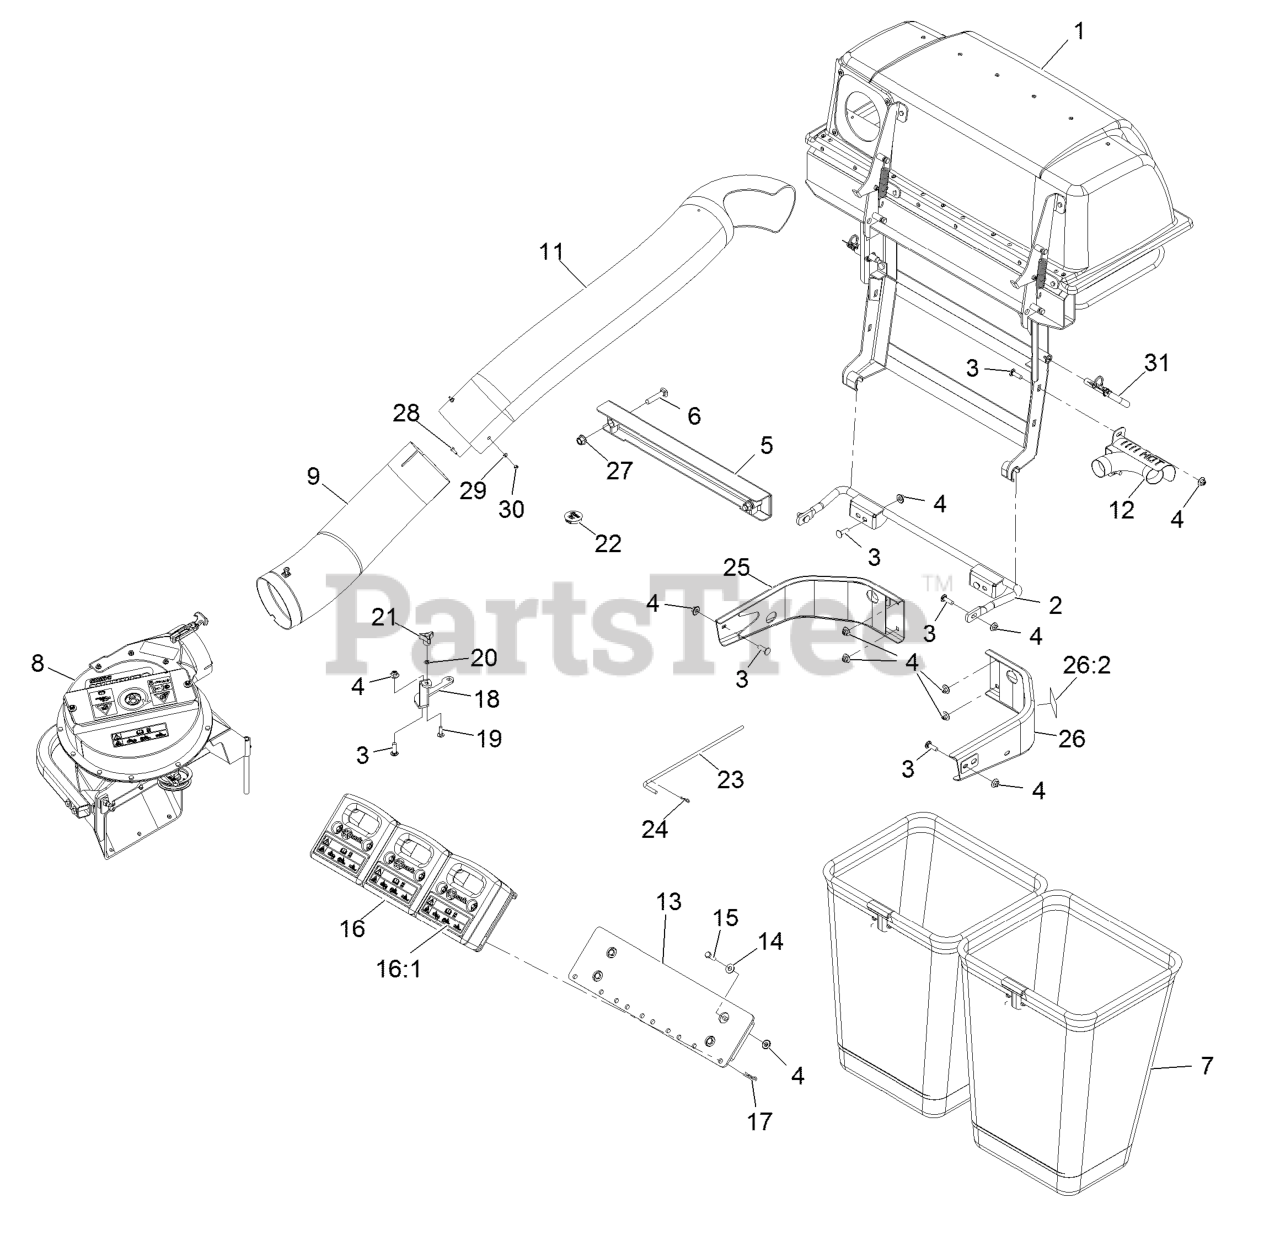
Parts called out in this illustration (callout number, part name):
2	Mount-Bagger, Lower
3	Bolt-Carriage 3/8-16 X 1 1/4
4	Nut-Nyloc 3/8-16 Flg
5	Mount-Bagger, Upper
6	Bolt-Carriage 1/2-13 X 2 1/2
7	Bag And Frame ASM
8	ASM, Blower Small - Svc Only
9	Lower Tube ASM
11	Tube-Upper
12	Exhaust Diverter ASM
13	Wld, Mount Toeboard Weight
14	Washer-3/8 Std
15	Screw-HH 3/8-16 X 1 1/4
16	Asm, Weight (103-6364-01) W/Decals
16:1	Decal-Warning Weight
17	Hairpin-Cotter
18	Bracket, Small Uv Belt Cover
19	Bolt-Carriage 5/16-18 X 1
20	Ring-Bolt Retaining
21	Knob-3 Prong
23	Pin, Chute Pivot
24	Hairpin-Cotter
25	Bumper-RH
26	LH Bumper ASM
26:2	Decal-Warning
27	Nut-Lock 1/2-13
28	Screw-HWH #10-24 X 3/4
29	Washer-#10 Std
30	Nut-Nyloc #10-24
31	Pin-Mount, Bagger
